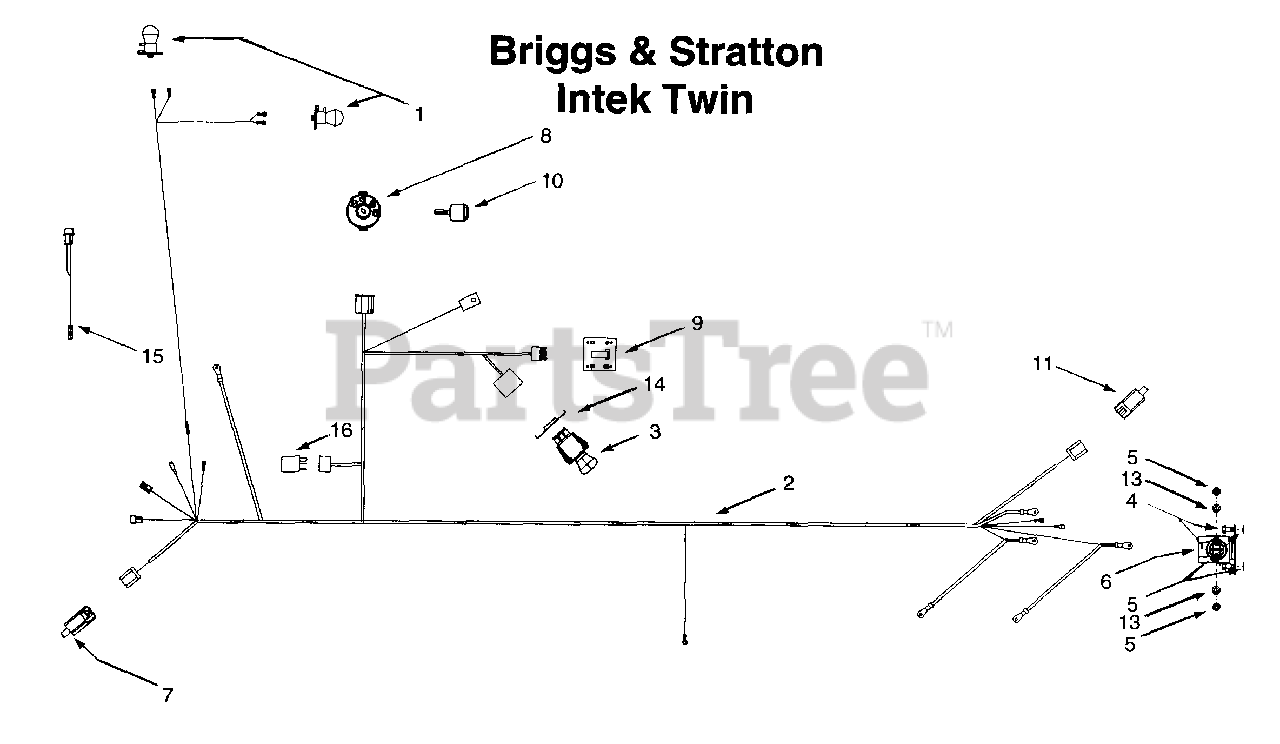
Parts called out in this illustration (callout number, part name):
1	Bulb/Socket Headlight Assembly
2	Wiring Harness
3	Electric PTO Switch
4	Self Tapping Screw, 1/4-20 x .5
5	Hex Nut, 1/4-20
6	Solenoid, 12-volt, 100 Amp
7	Snap Mount Safety Interlock Switch
8	Ignition Switch
9	Indicator Monitor / Hour Meter
10	Ignition Key w/Plastic Cover
11	Safety Plunger Switch
13	Lock Washer, 1/4
14	Retainer Bracket
15	Alternator Adapter
16	Electric PTO Relay
